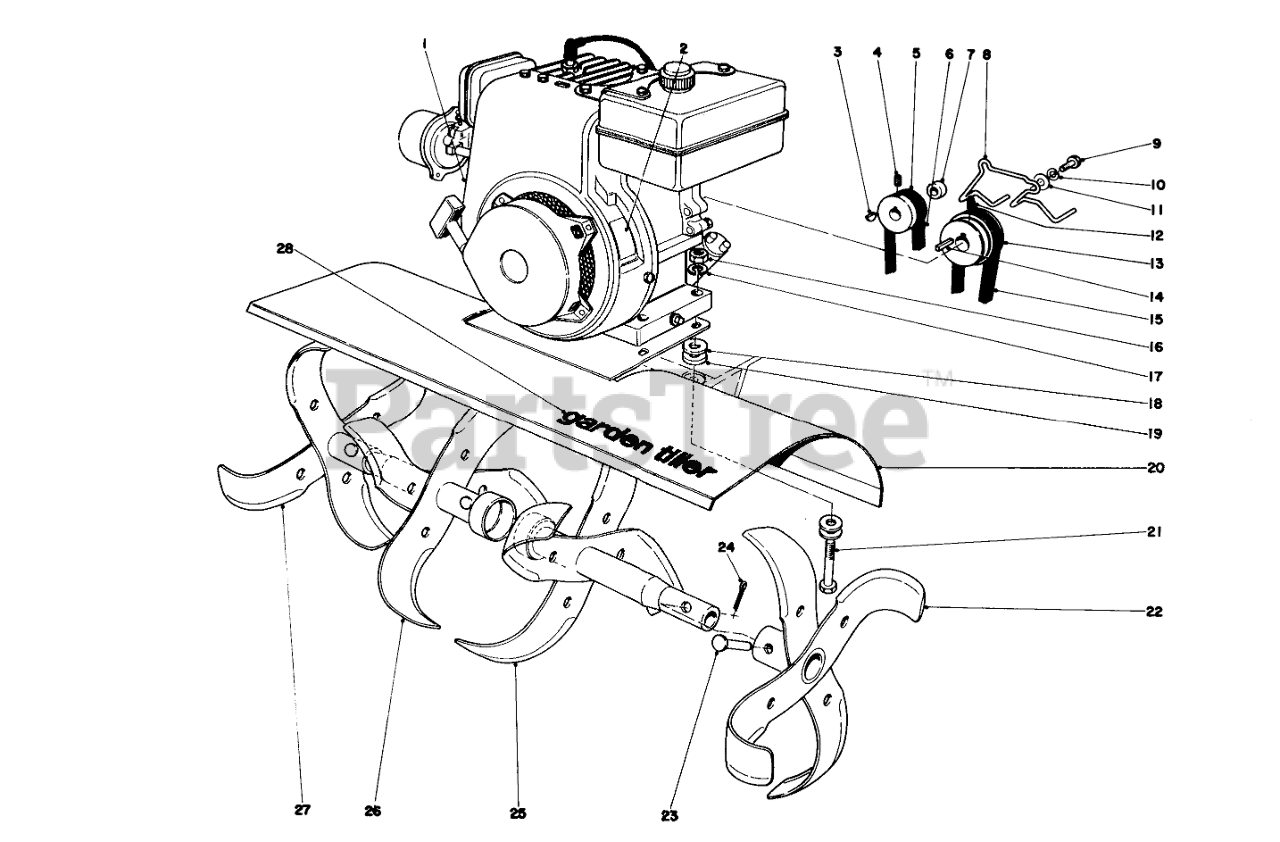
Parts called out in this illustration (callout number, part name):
1	Engine
2	Toro Lubrication
3	HI PRO KEY
4	Set Screw
5	PULLEY
6	Belt Reverse
7	Spacer
8	Belt Guide Upper
9	SCREW-HH
10	WASHER-LOCK
11	WASHER-FLAT
12	SCREW-SET, HSH
13	Engine Pulley
14	KEY-SQUARE
15	Belt
16	NUT-HEX
17	WASHER-LOCK
18	WASHER-FLAT
19	WASHER-FLAT
20	Shield
21	SCREW-HH
22	LH OUT SLASH TINE WA
23	TINE PIN
24	PIN-COTTER
25	Inner Tine L.H.
26	Inner Tine R.H.
27	RH OUT SLASH TINE EA
28	Decal
